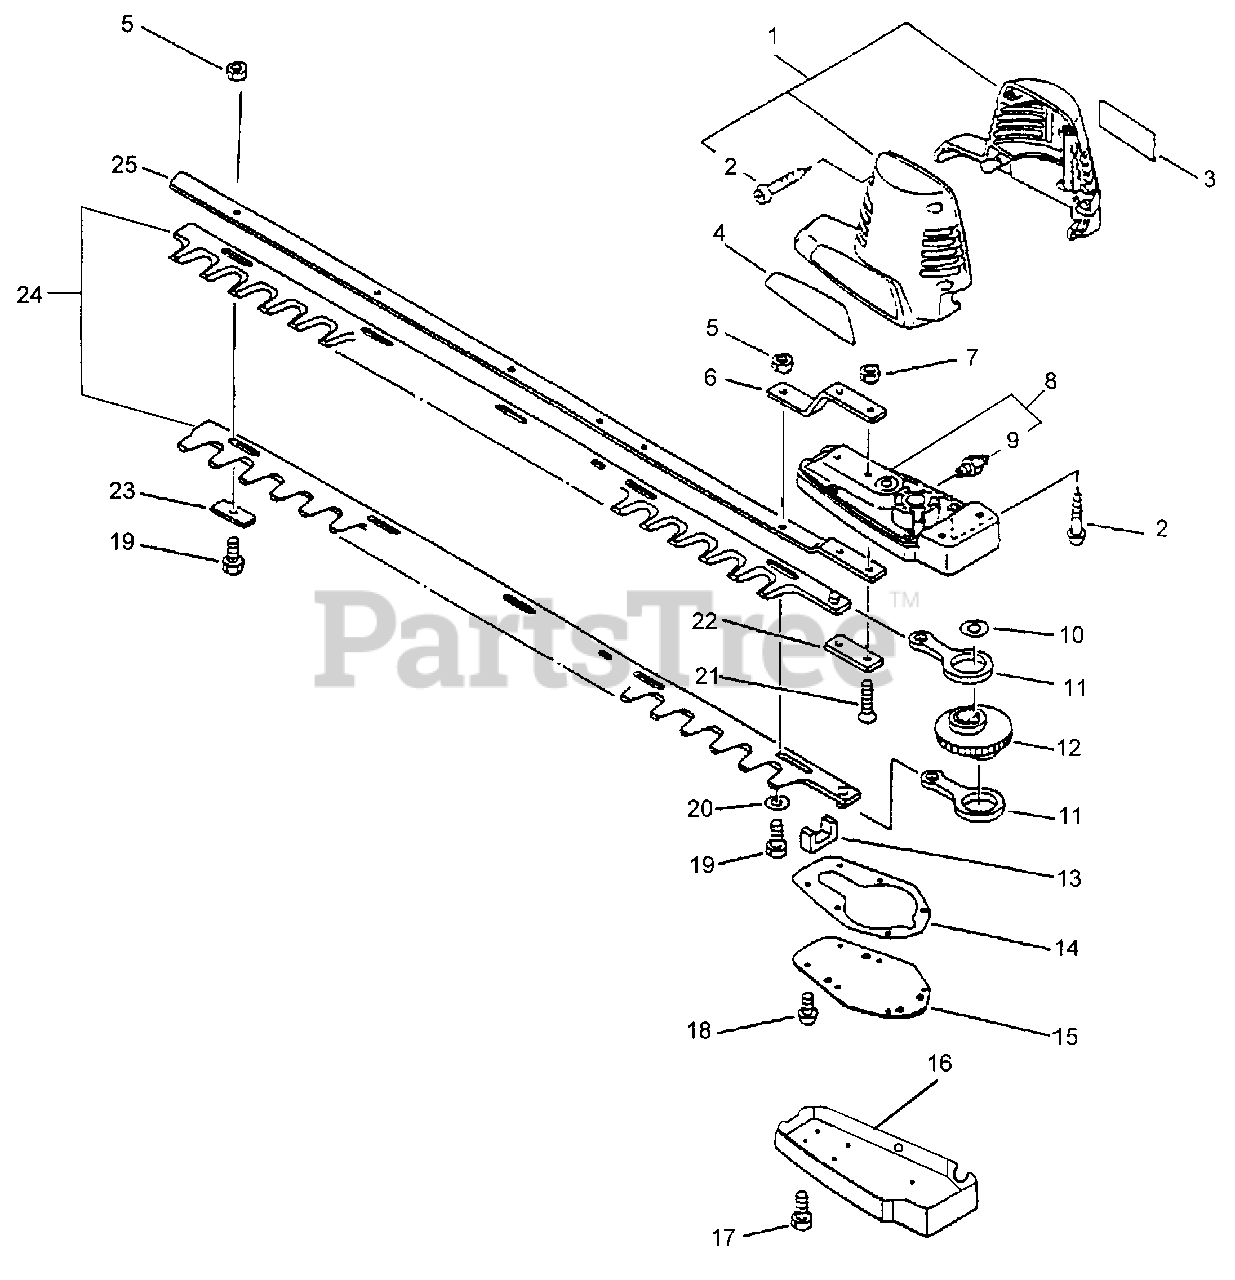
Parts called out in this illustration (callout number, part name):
1	MOTOR CASE KIT
2	SCREW - 4X22
3	LABEL - CAUTION
4	LABEL - MODEL
5	LOCKNUT - 6
6	PLATE, ANGLE
7	LOCKNUT - 6
8	CASE, GEAR
9	FITTING, GREASE
11	ROD, CONNECTING
12	GEAR - DRIVE
13	SEAL, FELT
14	GASKET, GEAR CASE
15	LID, GEAR CASE
16	LID, GEAR CASE
17	SCREW - 4X16
18	SCREW - 4X12
19	BOLT - 6X18
20	WASHER - 6
21	SCREW - 6X25
23	INSULATOR
24	TRIMMER BLADE SET
25	SUPPORT, BLADE
